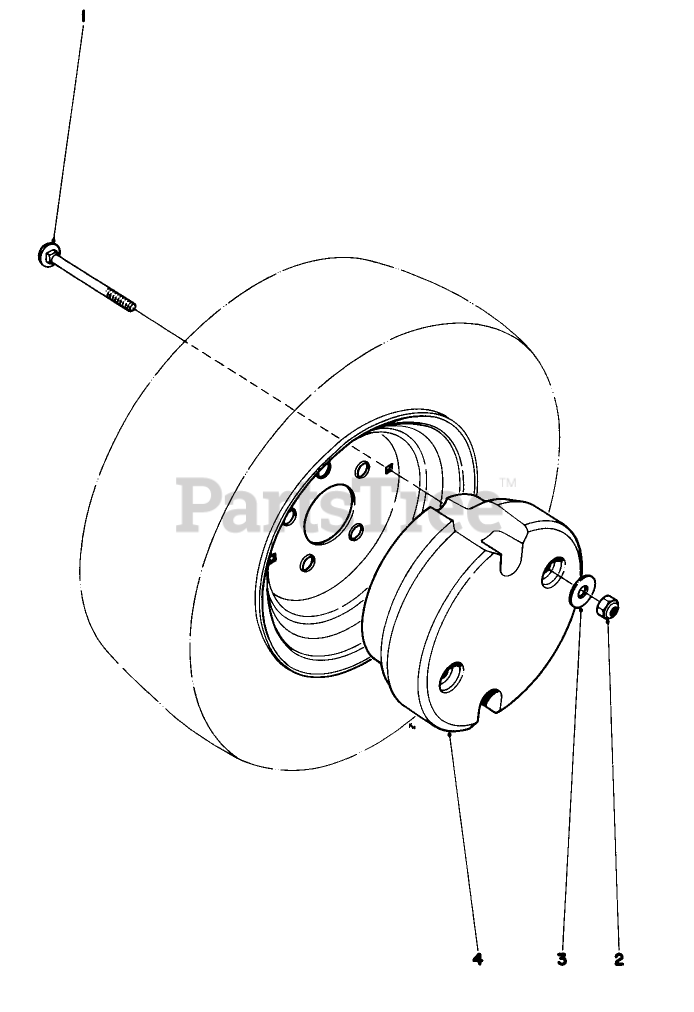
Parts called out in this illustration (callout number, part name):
1	SCREW-CARR
2	NUT-LOCK, NI
3	WASHER-FLAT
4	Wheel Weight
